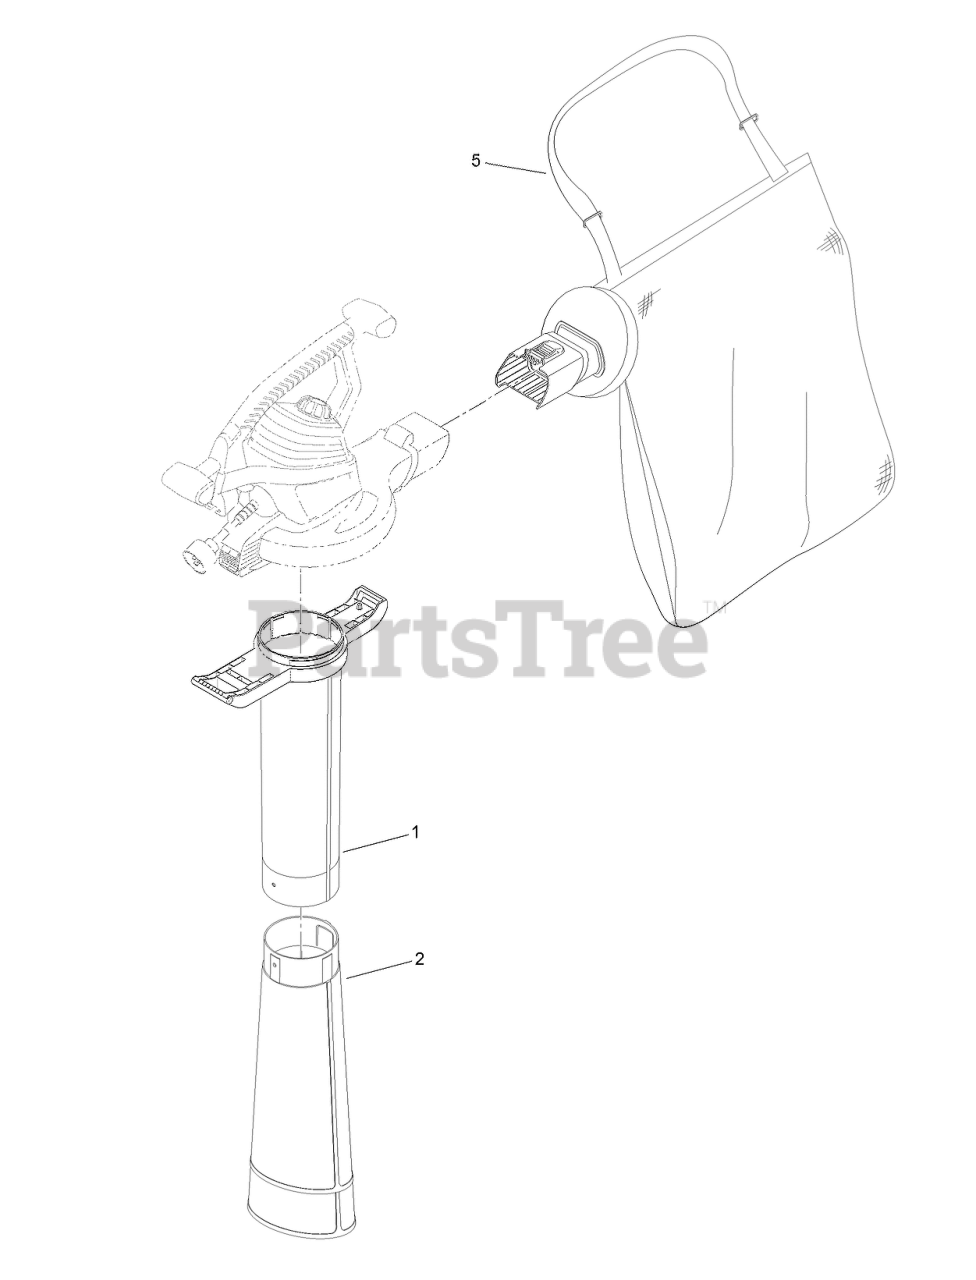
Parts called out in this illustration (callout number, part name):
1	TUBE-VACUUM, UPPER
2	TUBE-VACUUM, LOWER
5	BOTTOM ZIP BAG ASM
